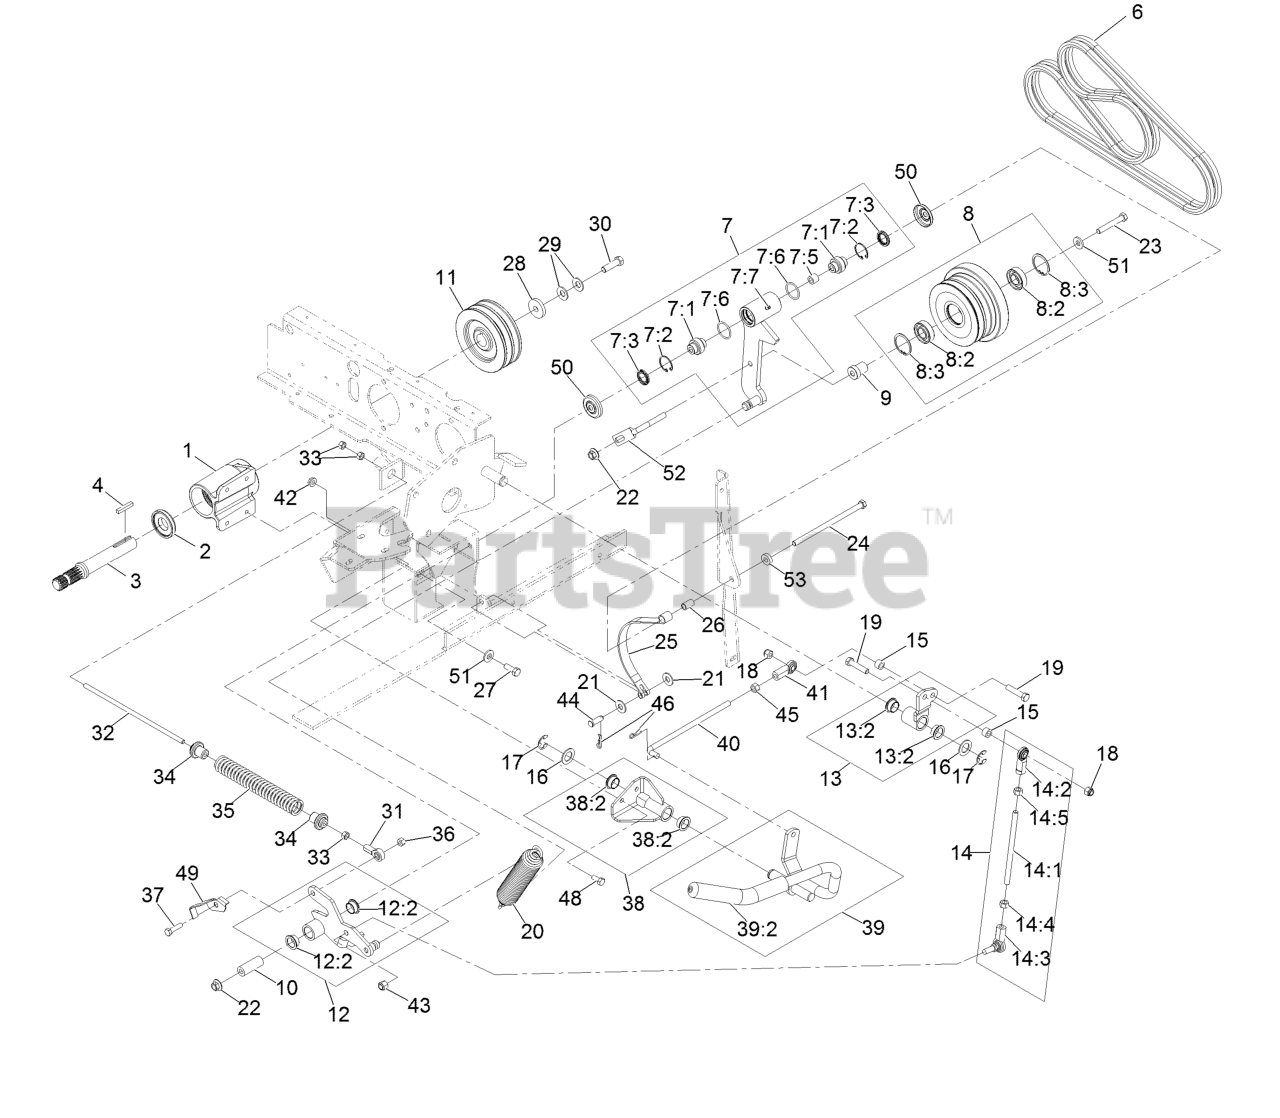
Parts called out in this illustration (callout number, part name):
1	Jackshaft ASM
2	Spacer-Guard, Bottom
3	Jackshaft
4	Key-Square
6	Belt, Matched Pair
7	Idler Pivot ASM
7:1	Bearing-Spherical
7:2	Ring-Snap
7:3	Seal-Lip, Single
7:5	Bushing-Lever, Lift
7:7	Fitting-Grease
8	Idler Sheave ASM
8:2	Bearing-Ball
8:3	Ring-Retaining
9	Spacer-Idler
10	Bushing
12	Arm ASM
12:2	Bushing-Bronze
13	Arm ASM
13:2	Bushing-Bronze
14	Clutch Link ASM
14:1	Rod-Linkage
14:2	Joint-Ball End, LH
14:3	Balljoint-RH
14:4	Nut-Hex
14:5	Nut-Hex, LH
18	Nut-Lock, NI
19	Screw-HH
20	Spring-Extension
21	Washer-Flat
23	Screw-HH
24	Screw-HH
25	Band-Brake
27	Screw-HH
28	Washer-Clutch
29	Washer-Spring
30	Screw-HH
31	Balljoint-RH
32	Linkage-Rod, PTO Brake
33	Nut-Hex
34	Bushing-Spring
35	Spring-Brake
36	Nut-Lock, NI
37	Screw-HH
38	Pivot ASM
38:2	Bushing-Bronze
39	PTO Handle ASM
39:2	Grip-Lever, Control
40	Link-Handle
41	Joint-Ball, End
43	Nut-Lock
44	Pin-Clevis
45	Nut-Hex
46	Pin-Cotter
48	Screw-HH
49	Switch-Flag
50	Guard-Top
51	Washer-Belleville
52	Guide-Belt
53	Spacer
